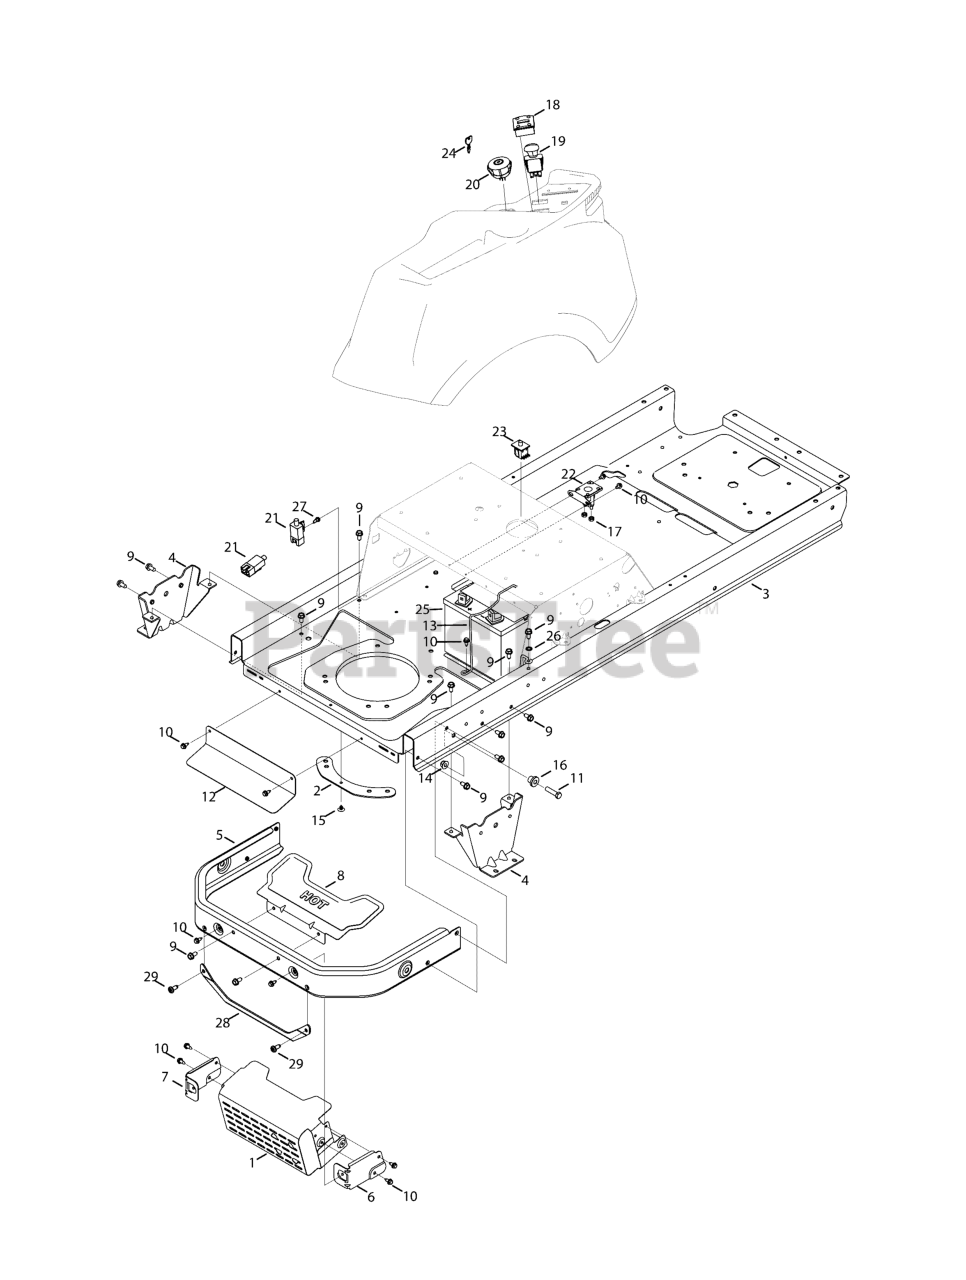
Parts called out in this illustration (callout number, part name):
1	ASSEMBLY, Muffler Shield
2	PLATE, Retainer
3	ASSEMBLY, Frame
4	BRACKET, Transmission Mounting
5	BUMPER, Bumper
6	BRACKET, Muffler Mounting Shield, RH
7	BRACKET, Muffler Mounting Shield, LH
8	SHIELD, Muffler
9	SCREW, 5/16-18 X .750, Hex Washer
10	SCREW, 1/4-20 X .625, Hex Washer
11	SCREW, 3/8-16 X 1.25, Hex
12	SHIELD, Lower Heat
13	ROD, Battery
14	NUT, 3/8-16, Flanged Lock, GR5
16	SPACER, .38 X 1.0 X .70, Shoulder
17	NUT, Flange Nylock , 1/4-20
18	HOUR METER/SERVICE MINDER
19	SWITCH, Electric PTO
20	SWITCH, Key (Ignition)
21	SWITCH, Interlock
22	SOLENOID
23	SWITCH, Seat
24	ASSEMBLY, Key
25	BATTERY
26	WASHER, 5/16, EXT., Lock
27	SCREW, #10-32 X .500, Shoulder
28	BRACKET, Rear Muffler Shield
29	SCREW, 5/16-18, 0.750, Self-Tapping
